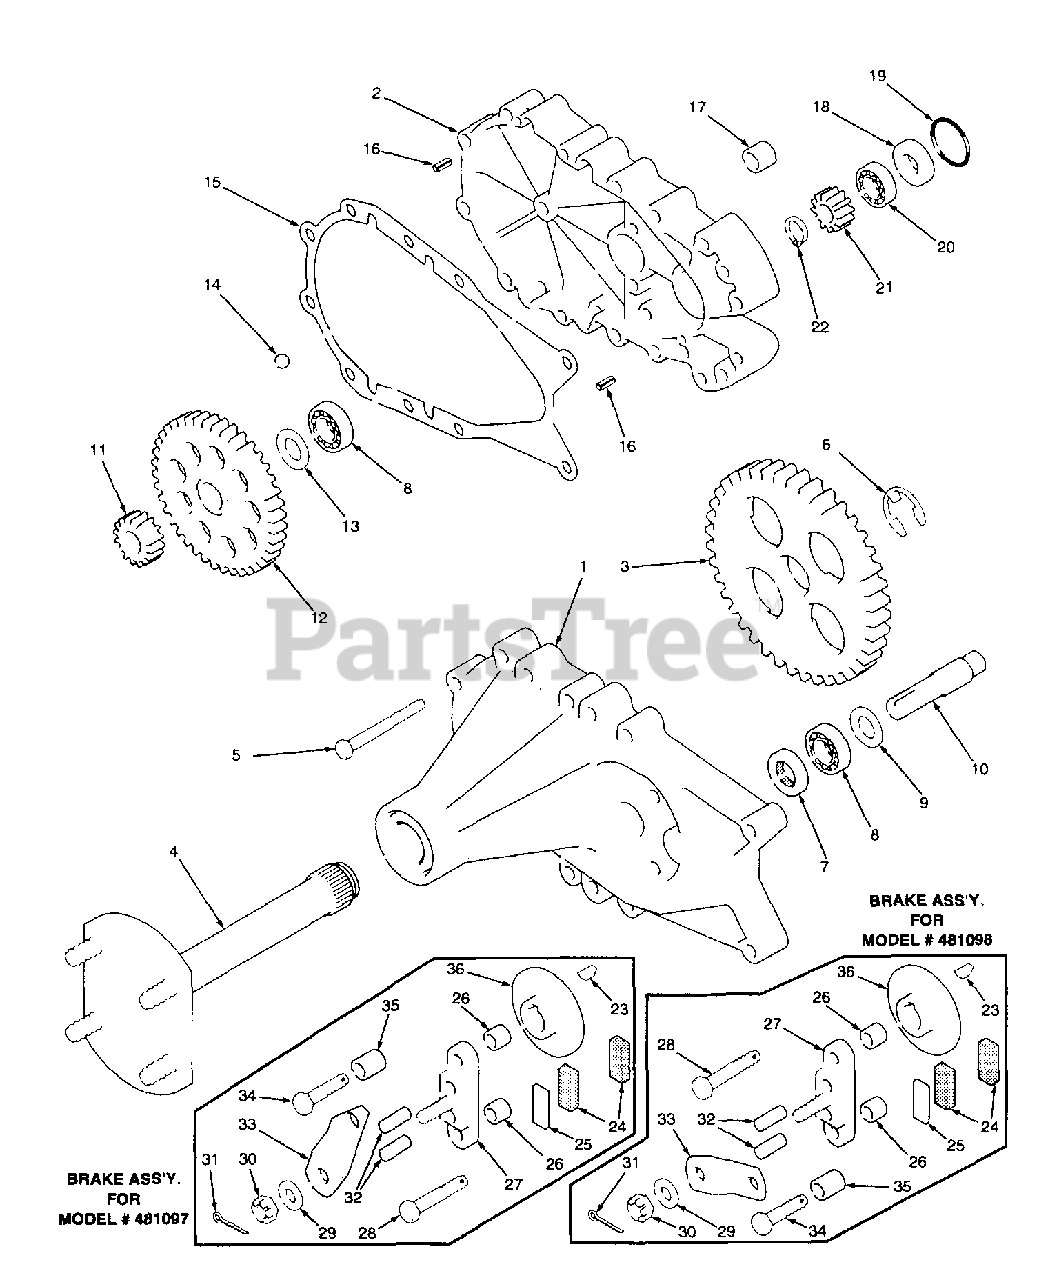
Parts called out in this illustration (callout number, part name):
1	Axle Housing Assembly
2	Hydro Mount Housing
3	Splined 72 Tooth Final Drive Gear
4	Axle Shaft Assembly
5	Bolt, 1/4-20 x 2-1/2" Hex Head
6	E-Ring .875
7	Oil Seal, 1.25 x .625
8	Ball Bearing, .62 ID x 1.38 x .44
9	Washer, HT .62 ID x 1.0 OD x .05 Thick
10	Brake Shaft (Splined)
11	Splined Reduction Gear, 17 Tooth
12	Splined 60 Tooth Gear
13	Washer, HT .62 ID x 1.0 OD x .05 Thick
14	Ball, 3/8" Diameter
15	Gasket, Housing
16	Pin, Spring 3/16" x 1/2" x 12" Long
17	Mounting, Spacer
18	Bearing, Spacer
19	O-Ring
20	Ball Bearing, 15mm x 35mm x 11mm
21	Input Gear, 11 Tooth
22	Retaining Ring
23	Key, Hi Pro 3/16 x 5/8
24	Puck, Brake
25	Plate, Puck
26	Brake Spacer
27	Brake Yoke Assembly
28	Bolt, 1/4-20 x 1-1/2" w/Patch
29	Washer, 7/16 x 7/8 OD x .06 HT
30	Nut, Castle 5/16-24 PL
31	Pin, Cotter
32	Pin, Brake Actuating
33	Arm, Brake Actuator (LH Assy.)
33	Arm, Brake Actuator (RH Assy.)
34	Bolt, 1/4-20 x 2-1/2"
35	Spacer, Torsion Spring
36	Disc, Brake
